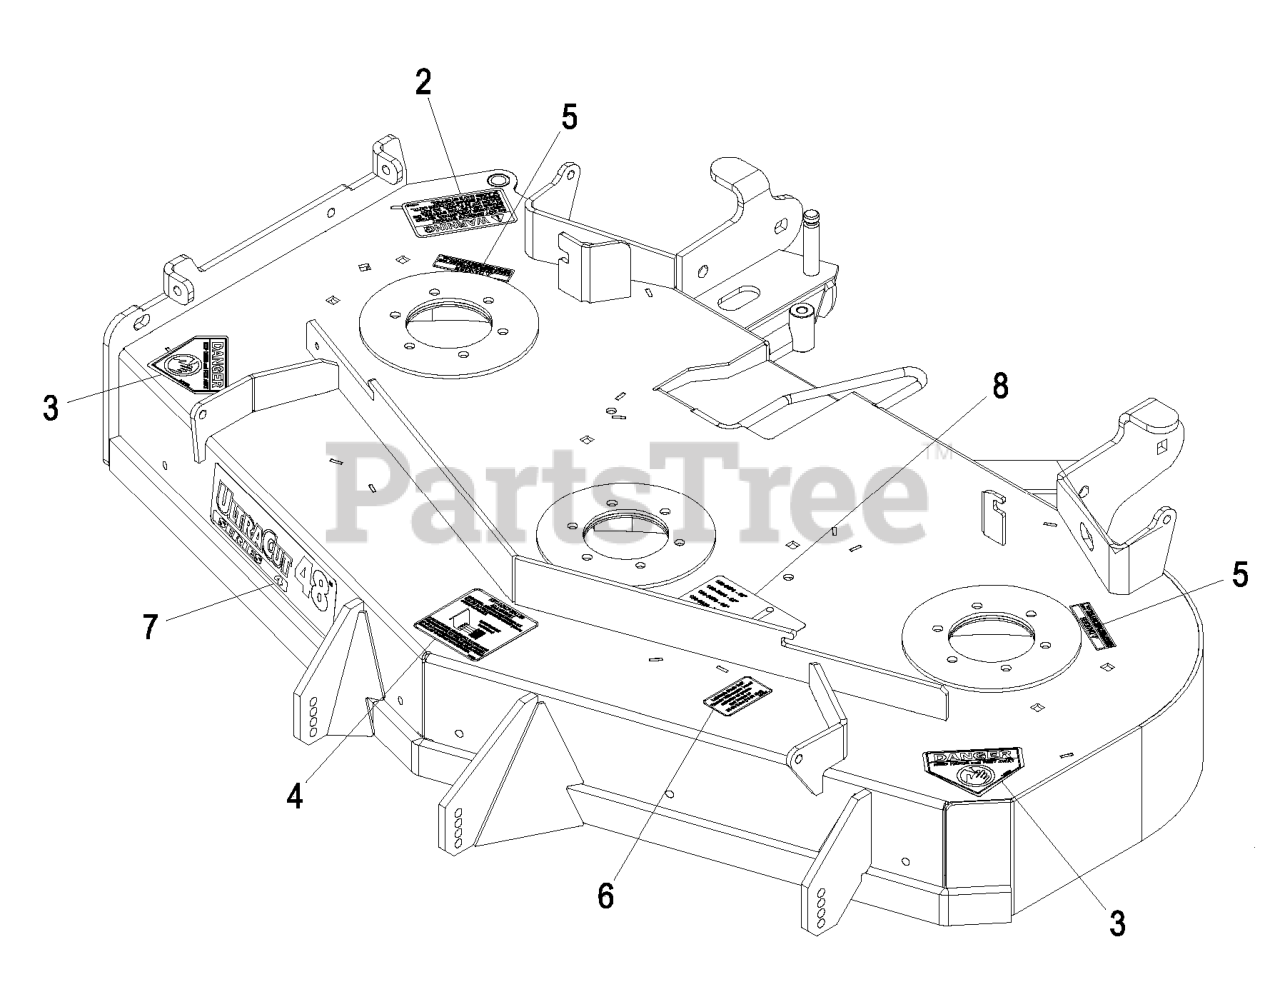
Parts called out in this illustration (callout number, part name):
2	DECAL-WARNING, DISCHARGE
3	DECAL-DANGER
4	DECAL,ANTISCALP
5	DECAL-COVER, MISSING
6	DECAL,BOLT TORQUE
7	DECAL,ULTRACUT 48 SERIES
8	DECAL,BELT ROUTING
